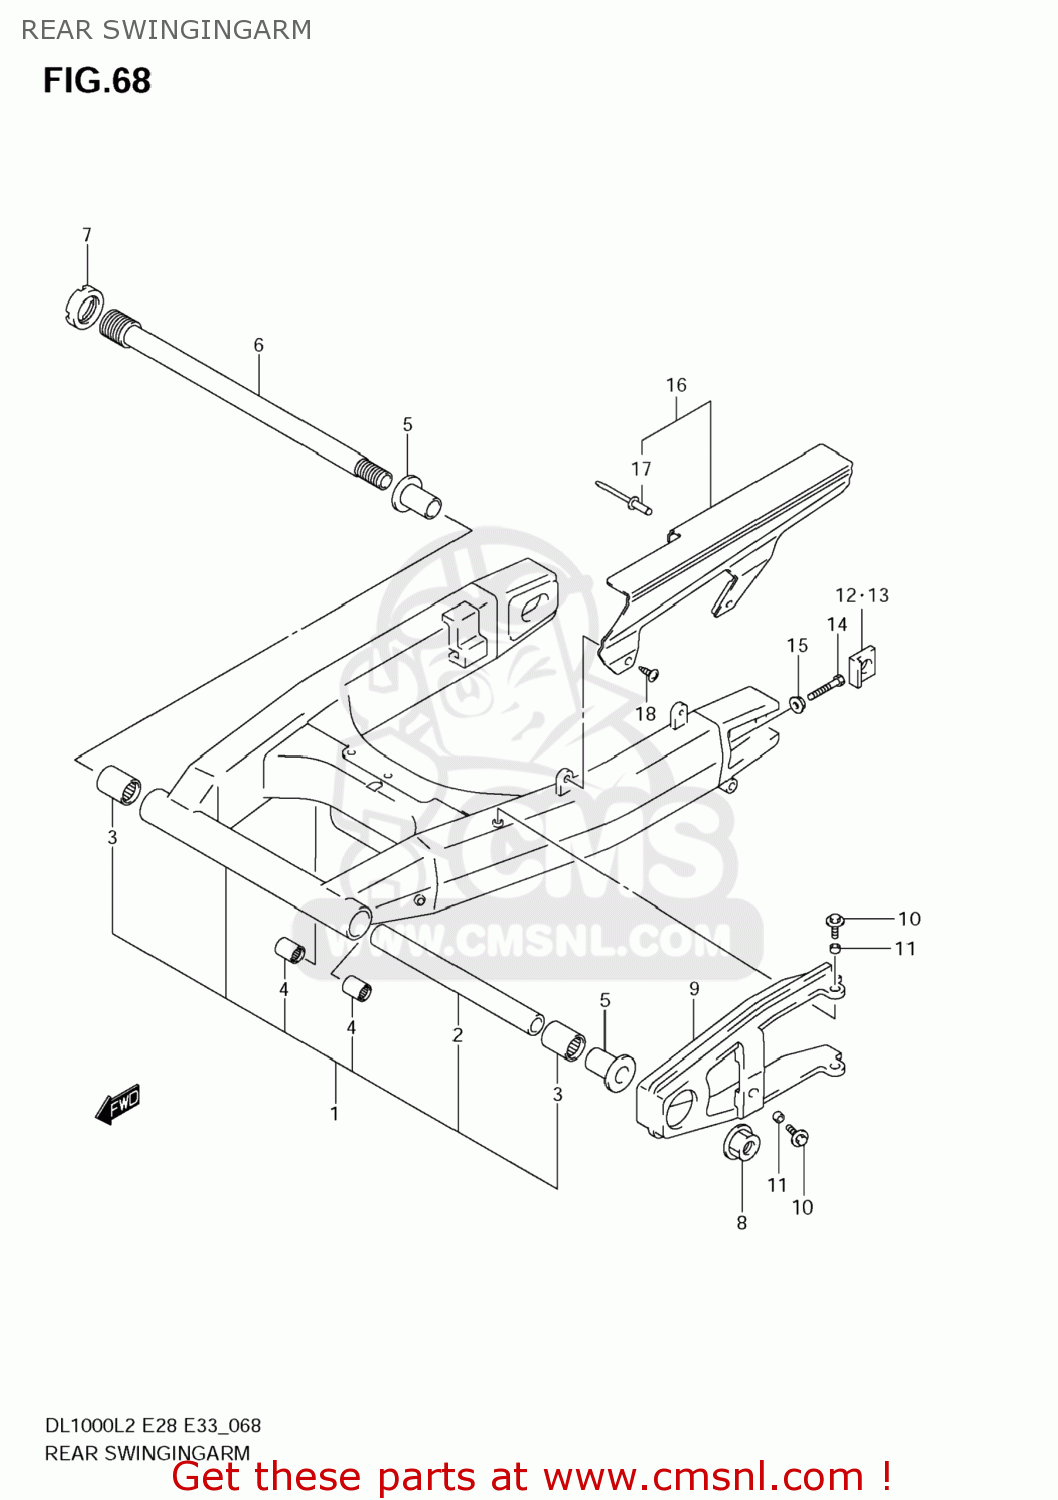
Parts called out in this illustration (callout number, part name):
1	SWINGING ARM ASSY, REAR
2	SPACER(20.8X27.2X196.7)
3	BEARING(25X33X35)
4	BEARING(17X24X25)
5	SPACER,RR SWGARM PIVOT BERRING
6	SHAFT,RR SWINGINGARM PIVOT
7	NUT,REAR SWING ARM PIVOT BOLT
8	NUT
9	BUFFER,CHAIN TOUCH DEFENSE
10	BOLT(6X20)
11	SPACER(6.5X9X5)
12	WASHER,CHAIN ADJUSTER
13	WASHER,CHAIN ADJUSTER
14	BOLT(8X50)
15	NUT
16	CASE,CHAIN
17	RIVET
18	SCREW(6X16)
